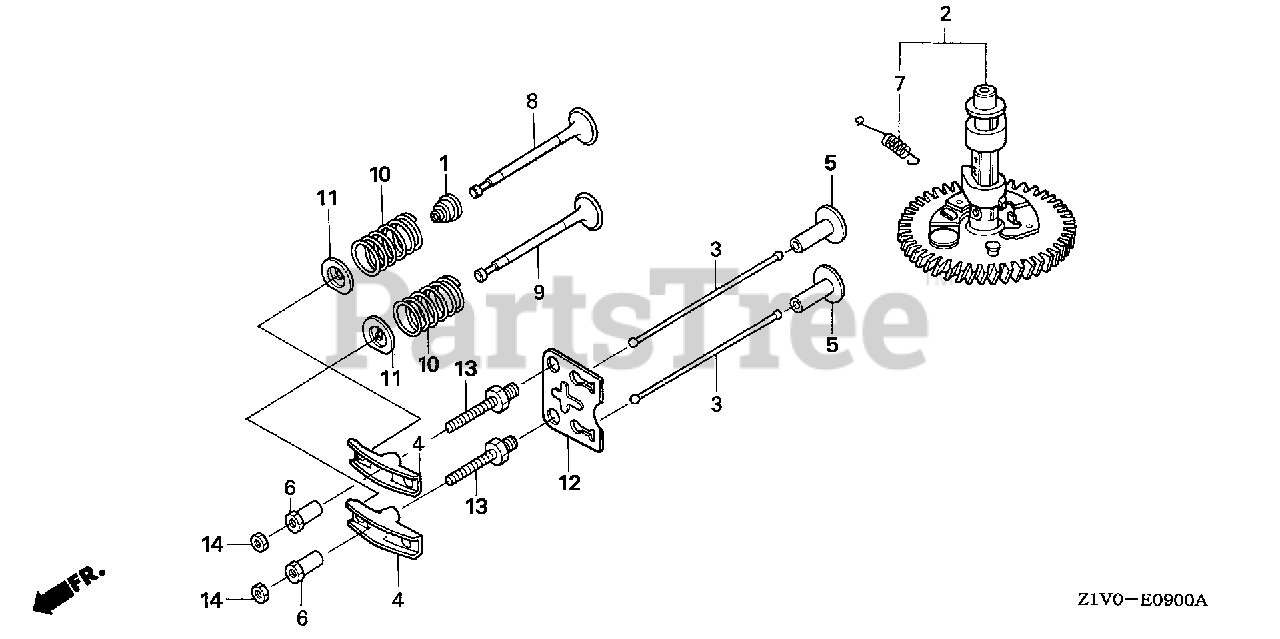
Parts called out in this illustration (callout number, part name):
1	SEAL, VALVE STEM
2	CAMSHAFT ASSY.
3	ROD, PUSH
4	ARM, VALVE ROCKER
5	LIFTER, VALVE
6	PIVOT, ROCKER ARM
7	SPRING, WEIGHT RETURN
8	VALVE, IN.
9	VALVE, EX.
10	SPRING, VALVE
11	RETAINER, IN. VALVE SPRING
12	PLATE, PUSH ROD GUIDE
13	BOLT, PIVOT (8MM)
14	NUT, PIVOT ADJUSTING
